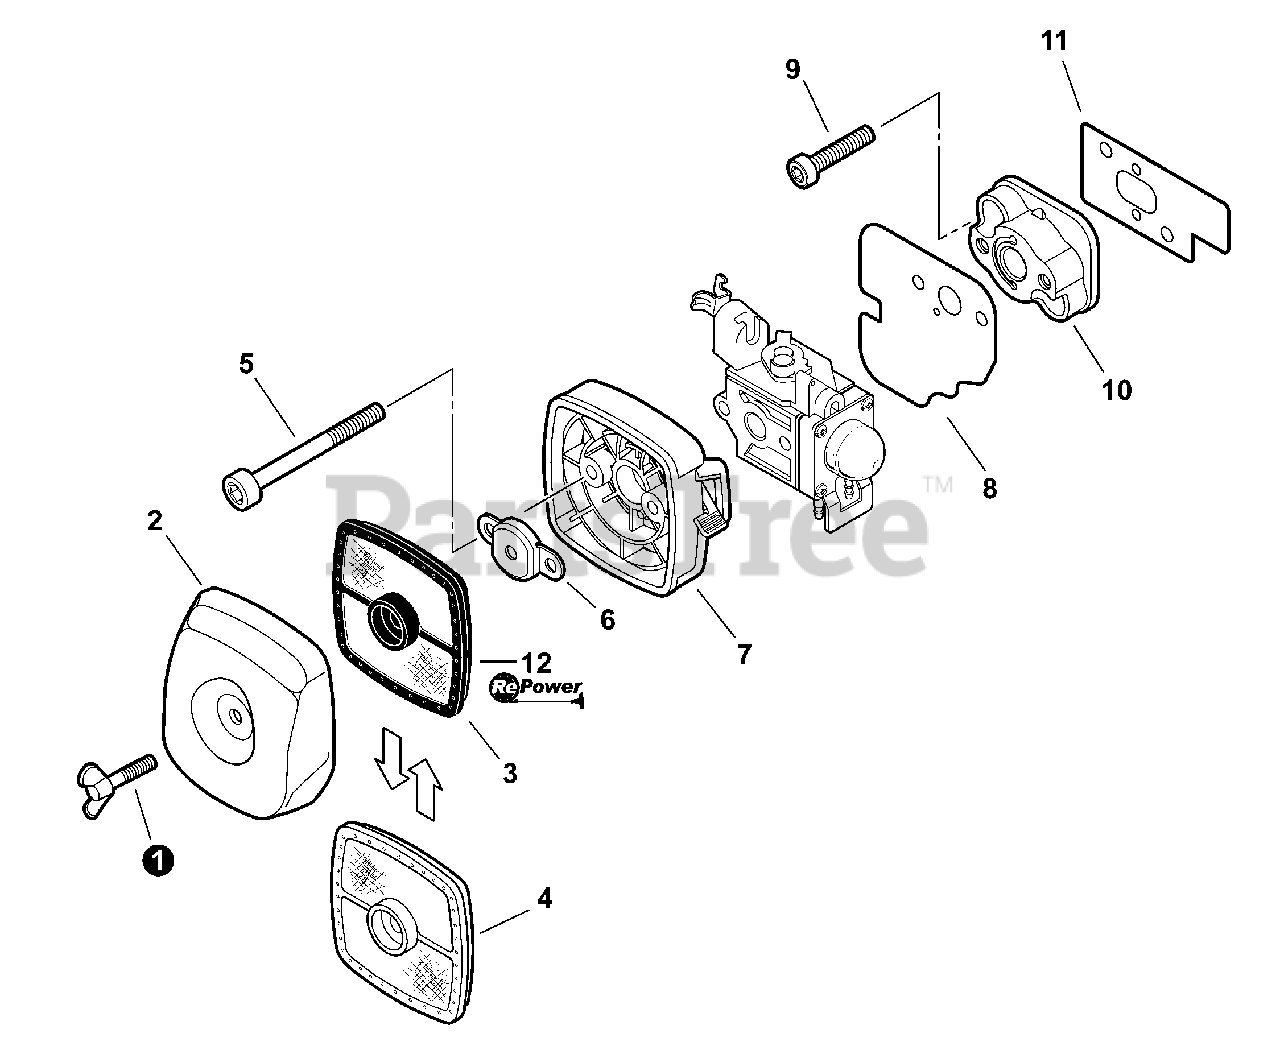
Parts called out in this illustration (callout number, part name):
1	THUMBSCREW
2	COVER, AIR FILTER - BLACK
3	FILTER, AIR - DOUBLE LAYER
4	FILTER, AIR - SINGLE LAYER
5	SCREW - 5×65 -- TORX
6	PLATE, PREVENT
7	CASE, AIR CLEANER - BLACK
8	GASKET, INTAKE
9	SCREW - 5×25
10	INSULATOR, INTAKE
11	GASKET, INTAKE
12	RePower TUNE-UP KIT
